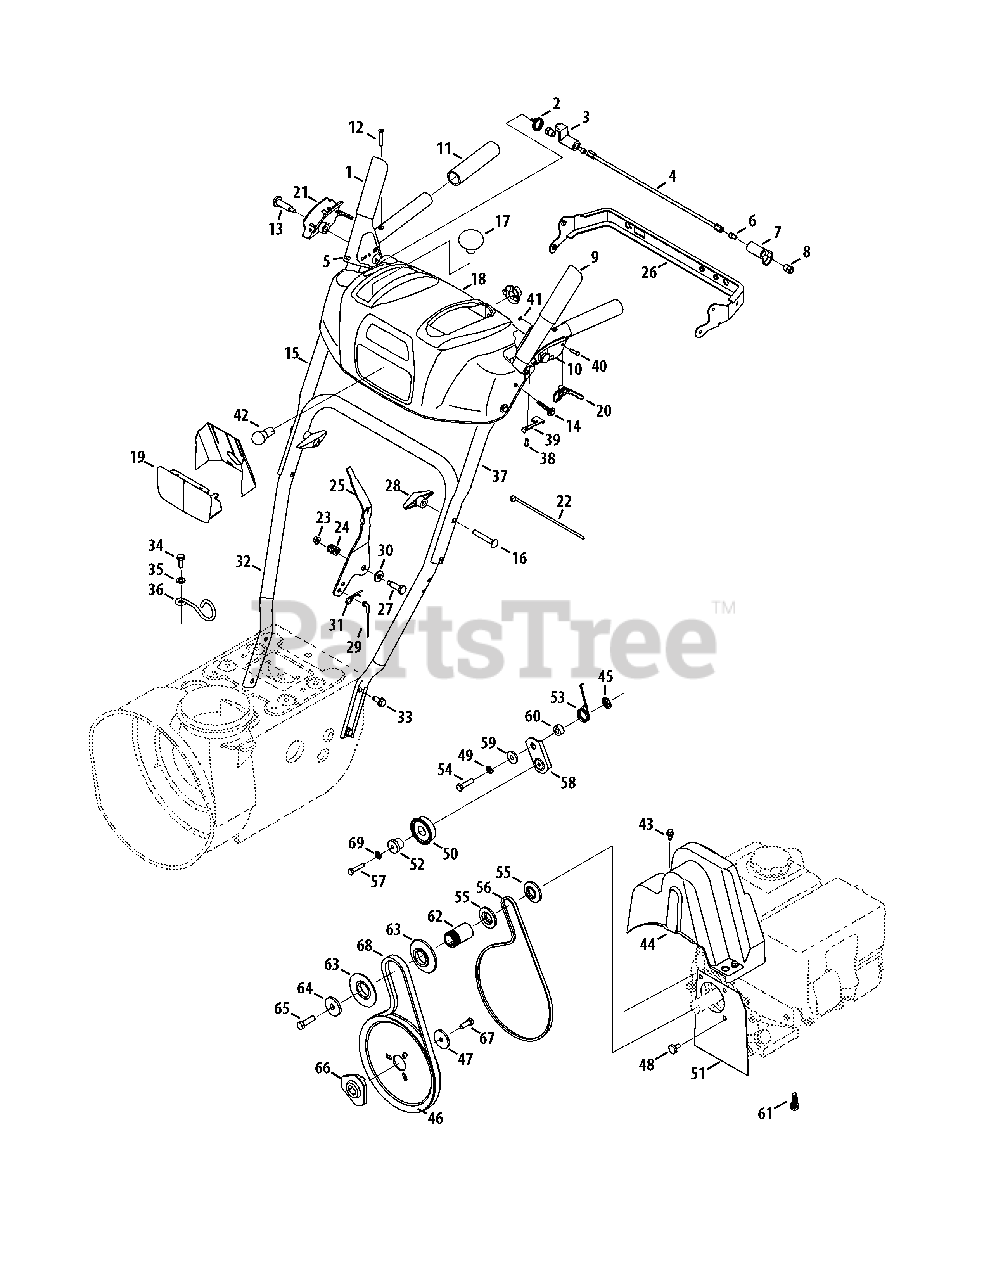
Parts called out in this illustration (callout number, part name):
1	Handle Engagement Ass’y RH
2	Torsion Spring
3	Lock Plate
4	Pivot Rod
5	Rubber Bumper
6	Screw, 1/4-20 x .500
7	Clutch Lock Cam
8	Shoulder Nut, 1/4-20
9	Handle Engagement Assembly LH
10	Handle Clutch Lock LH Assembly
11	Handle Grip
12	Screw, #10-24 x 0.375
13	Shoulder Screw, 1/4-20
14	Screw, 1/4-20 x 1.625
15	Upper Handle RH
16	Carriage Screw, 5/16-18 x 2.25
17	Shift Knob
18	Handle Panel
20	Steering Control
21	Handle Clutch Lock RH Assembly
22	Cable Tie
23	Flange Lock Nut, 1/4-20
24	Compression Spring
25	Shift Lever
26	Panel Bracket
27	Shoulder Screw
28	Wing Knob
29	Speed Selector Cable
30	Flat Washer
31	Click Pin
32	Lower Handle
33	Screw, 5/16-18 x 0.75
34	Screw, M8-1.25
35	Flat Washer, .330 x .630 x .0635
36	Cable Control Wire
37	Upper Handle LH
38	Screw, #8-16 x 0.50
39	Clutch Lock Spring
40	Pin, 3/16
41	Retainer Ring
42	Light Bulb
43	AB Screw, 1/4-20 x 0.625
44	Belt Cover
45	Push-on Nut
46	Auger Pulley
47	Flat Washer
48	Shoulder Screw
49	Lock Washer
50	Idler Pulley Assembly
51	Plt., Cvr.
52	Spacer
53	Torsion Spring
54	Hex Screw, 5/16-24 x 1.25
55	Pulley Half
56	Belt, Wheel Drive
57	TT Screw, 1/4-20 x 1.25
58	Drive Clutch Idler Bracket
59	Shoulder Spacer
61	TT Sems Screw, 3/8-16 x 1.0
62	Spacer
63	Pulley Half
64	Flat Washer
65	Hex Bolt, 3/8-24 x 1.25
66	Pulley Adapter
67	Hex Bolt, 5/16-24 x 0.875
68	V-Belt,.500 x 35.00 Lg
69	Lock Washer
